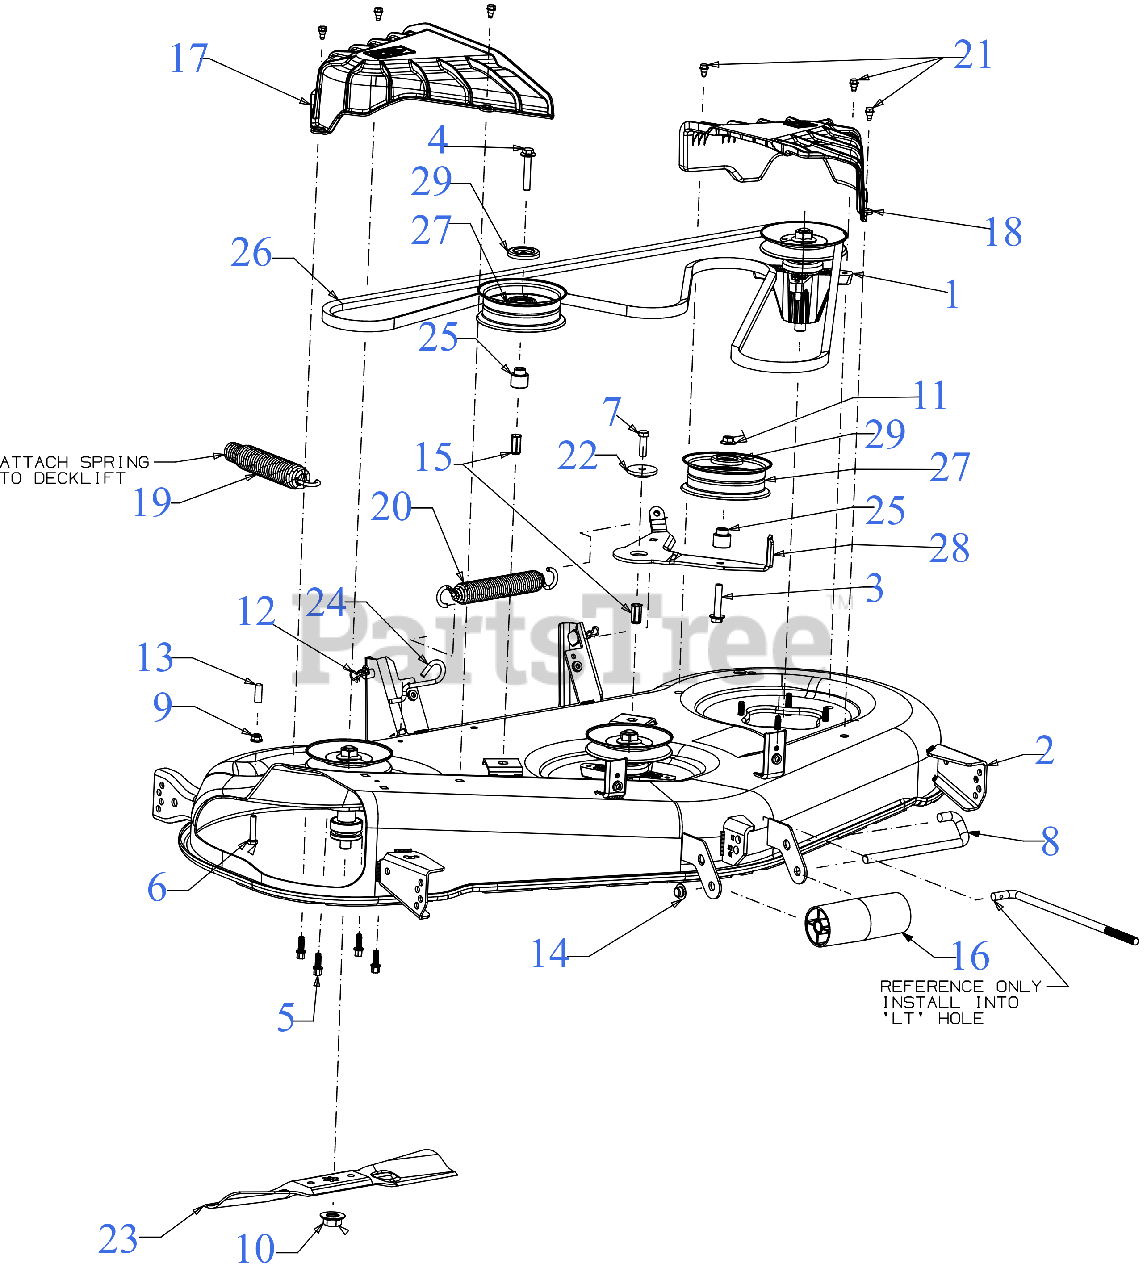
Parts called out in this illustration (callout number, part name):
1	BLADE SPINDLE ASSEMBLY W/PULLEY
1	Cub Cadet 50" SPINDLE ASSEMBLY (06981)
3	SCREW 3/8-16 x 2.0
4	SCREW 3/8-16 x 2.25 GR5
5	SCREW 5/16-18 x .875
6	SCREW 5/16-18 x 1.5 LG
7	SCREW 3/8-16 x 1.25 GR5
8	ROLLER PIN 1/2 x 7.31
9	FLANGE LOCK NUT 5/16-18
10	HEX NUT
11	FLANGE LOCK NUT
12	BOW TIE COTTER PIN
13	VINYL CAP
14	PUSH CAP
15	NUT RIVET 3/8-16
17	SPINDLE COVER (RH)
18	SPINDLE COVER (LH)
19	LIFT ASSIST SPRING (LARGE)
20	SPRING 1.25" DIA x 8.5" LONG
21	SHOULDER SCREW 1/4-20 x .50
22	SHOULDER SPACER
23	17.27" BLADE (2N1)
23	Cub Cadet 50" HI LIFT BLADE SET
23	Genuine Factory Parts 50" BLADE SET
23	50" 6 PT STAR LOW LIFT/SAND BLADE
23	Cub Cadet 50" LOWLIFT BLADE SET
23	Genuine Factory Parts 50" LOWLIFT BLADE SET
23	50" 6 PT STAR XTREME MULCH BLADE
23	Cub Cadet 50" XTREME BLADE SET
23	Genuine Factory Parts 50" XTREME MULCH BLADE SET
24	DECK SPRING HOOK
25	SHOULDER SPACER
26	V-BELT B SEC x 134
26	Cub Cadet 50" DECK BELT
26	Genuine Factory Parts 50" DECK BELT
27	IDLER PULLEY 4.50" DIA
28	IDLER PIVOT BRACKET
29	IDLER PULLEY CAP
